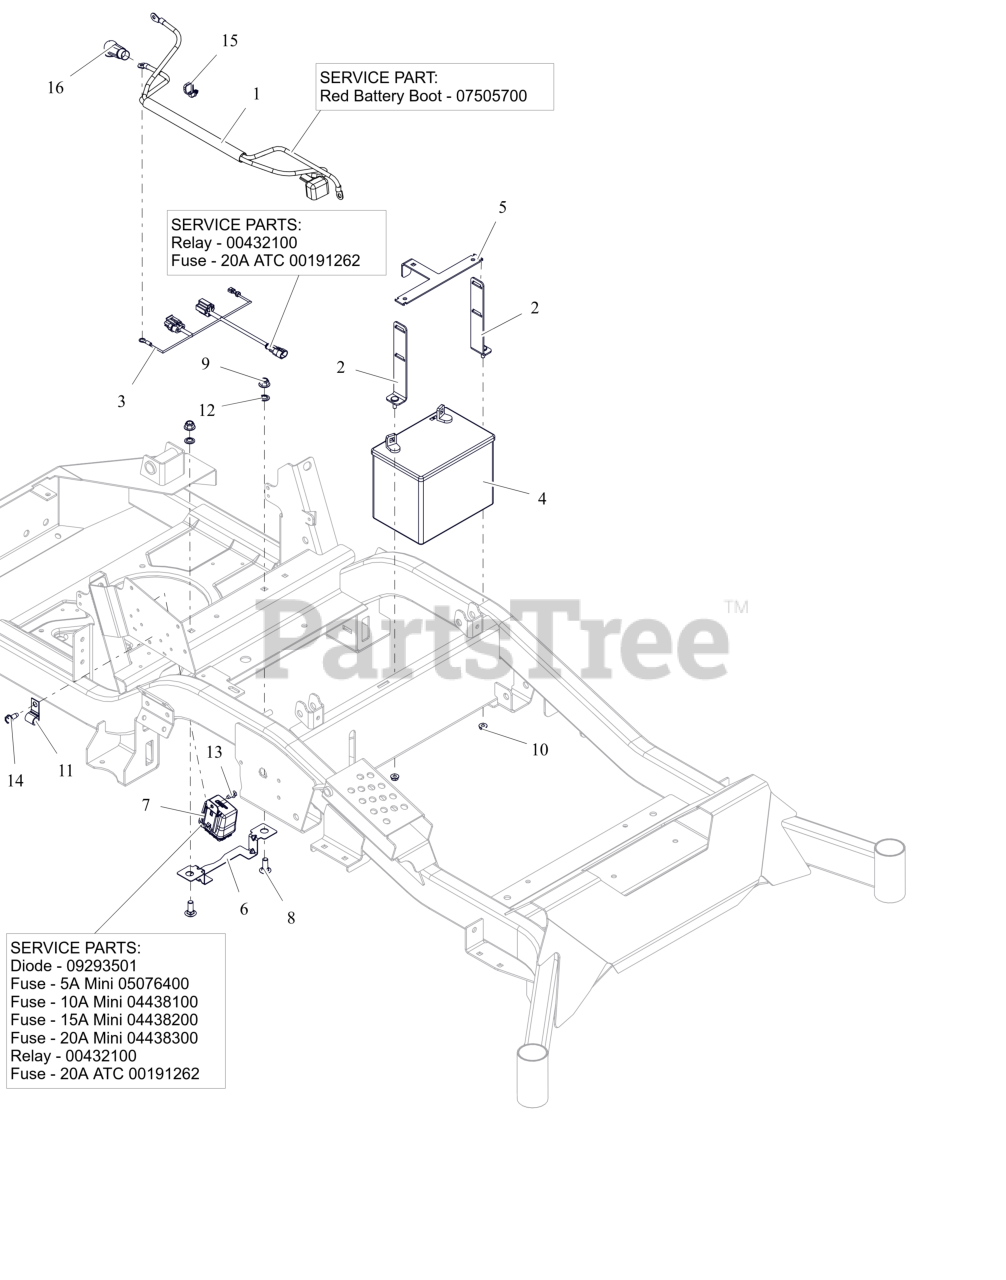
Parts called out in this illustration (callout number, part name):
1	HARNESS, BATTERY HD
1	INSULATOR
2	WMT,BATTERY MOUNT HOLD DOWN
3	HARNESS, STARTER ADAPTOR
3	RELAY,SEALED W/DIODE
3	FUSE, 20 AMP BLADE S/O
4	BATTERY, 300 CCA 10U1L
5	BRKT, BATTERY TIE DOWN
6	GUARD, ELECTRICAL HARNESS
7	HARNESS, WIRE
7	DIODE, CONNECTOR SHELL
7	FUSE, 5 AMP MINI-ATC
7	FUSE,10 AMP MINI-ATC
7	Fuse, 15 AMP MINI-ATC
7	FUSE,20 AMP MINI ATC
7	RELAY,SEALED W/DIODE
7	FUSE, 20 AMP BLADE S/O
8	BLT, RHSN .38-16X1.00 G5 ZCC
9	NUT,NYL-FLG .38-16 GF ZCC
10	NUT-LK-TOP-FLG .250-20 GF ZCC
11	J-CLAMP
12	NUT-PUSH .38 DIA. PAL ZINC
13	SCR-TAP .25-20X.50 HWH ZCC
14	SCR,TAP .312-18X.75 HWH TR ZCC
15	CABLE TIE W/ TREE (.25 HOLE)
16	BOOT, .65ID POS
